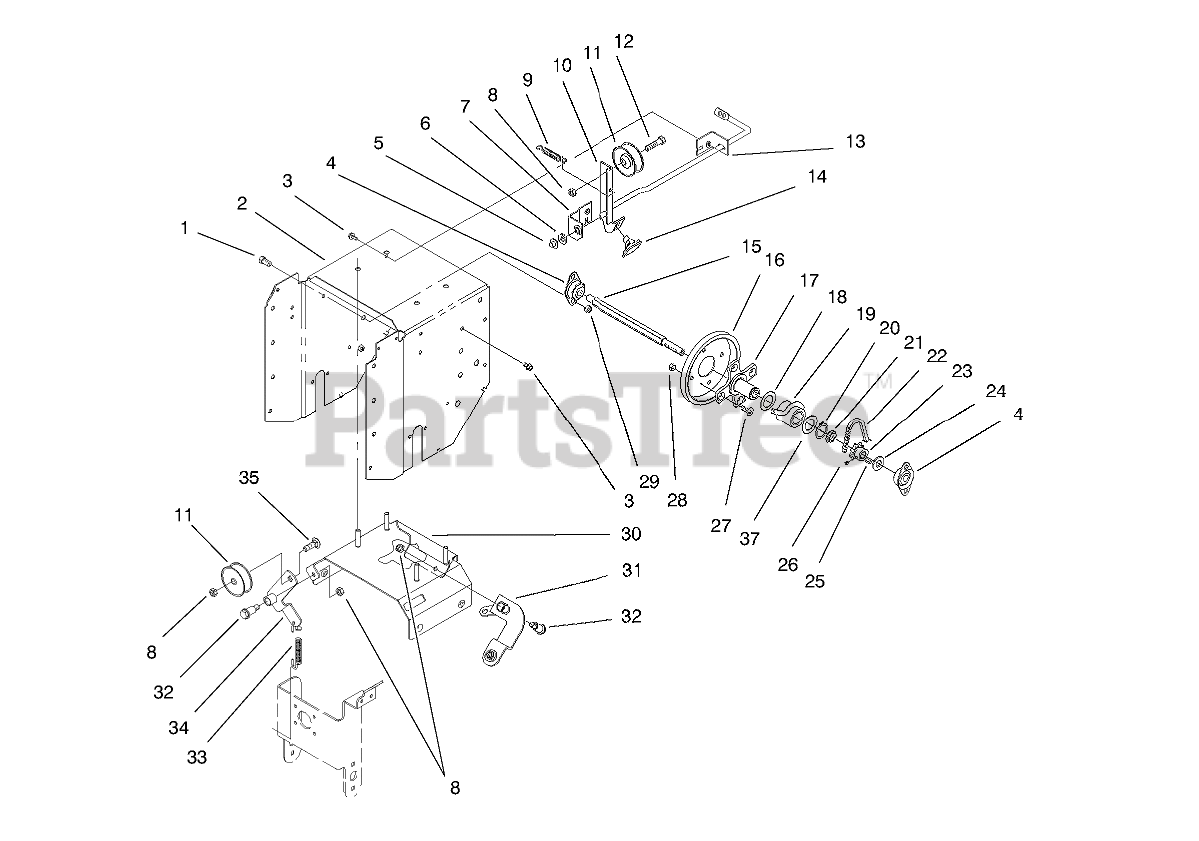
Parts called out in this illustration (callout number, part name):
1	SCREW-HH
2	Frame
3	SCREW-HWH
4	BEARING-TRIANGLE
5	RETAINER-PUSH ON
6	WASHER-FLAT
7	MOUNTING-CLUTCH ROD BRACKET
8	NUT-LOCK, NI
9	SPRING
10	Auger Clutch Rod
11	PULLEY-IDLER
12	SCREW-HH
13	MOUNTING-REAR CLUTCH ROD
14	PAD-BRAKE
15	SHAFT-HEX
16	FRICTION WHEEL
17	HUB-TRACTION DISC
18	Washer
19	SLIDER RING ASM
20	RING-RETAINING
21	SPACER
22	ROLLER-CHAIN
23	SPROCKET
24	WASHER-THRUST
25	KEY-SQUARE
26	SCREW-HSH
27	SCREW-HH
28	NUT-LOCK, NI
29	NUT-LOCK, NI
30	ASM-Brace/Stud
31	ASSEMBLY - SHIFT ARM
32	BOLT-SHOULDER
33	SPRING-EXTENSION IDLER
34	BRACKET-IDLER HUB
35	SCREW-CARR
36	WASHER
37	WASHER-THRUST
